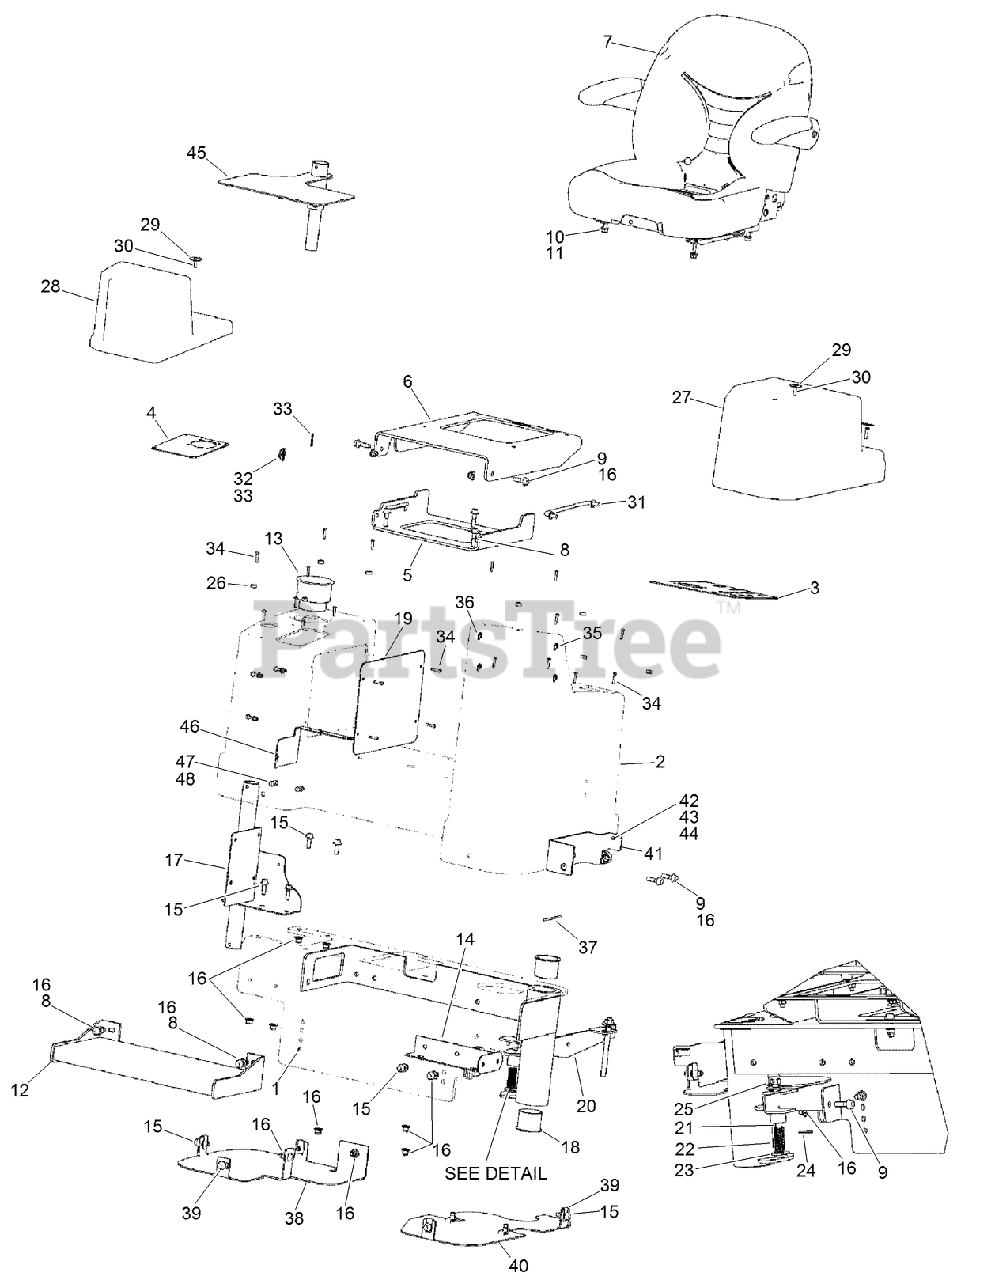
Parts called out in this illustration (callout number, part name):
1	WELDMENT - Operators Console
2	CONSOLE - Fiberglass
3	PLATE - Console/Switch
4	PLATE - Joystick Mount
5	PLATE - Seat Mount Bottom
6	PLATE - Seat Mount Top
7	OPERATOR SEAT ASM (STATIC)
8	SCREW-HHF
9	SCREW-HHF
10	WASHER - 0.406 x 0.750 x 0.119 in CST ZND
11	NUT - Hex .375 - 16 GR8 PHC
12	ASSEMBLY - Foot Rest
13	CUP-HOLDER
14	WELDMENT - Operators Console Support
15	SCREW-HH
16	NUT-FLANGE, NYLOCK
17	WELDMENT - Umbrella Mount
18	BEARING - Seat Pivot
19	PLATE - Seat Ins Panel
20	ARM - Seat Adjustment
21	ROD-SWING, SEAT
22	SPRING-PIVOT LOCK, SEAT
23	WASHER-FLAT
24	PIN-COTTER
25	NUT-Hex 0.500-13 GR5 ZND
26	GROMMET-RUBBER
27	COVER-PROTECTIVE, LEFT
28	COVER-PROTECTIVE, RIGHT
30	SCREW - Button Head (Allen)
31	ROD-PROP, SEAT
32	WASHER-FLAT
33	PIN - Cotter Hair Int 3/16 in ZND
34	SCREW - PHD Type 1, #10 - 24 x 1.00 CST ZND
35	SCREW - Hex Hd #10 - 24 x 0.875 CST PHC
36	NUT-#10-24 KEPS
37	PIN-COTTER
38	PLATE - Splash Guard
40	PLATE - Splash Guard
41	PLATE - Cord Retaining
42	CLIP - Tool
43	SCREW - PHd Type 1 #6 - 32 x 0.500 CST ZND
44	NUT - KEPS Ext T Wshr #6 - 32 UNC ZP
45	MOUNT - Locator
46	PLATE - Mount
47	SCREW, METRIC FLANGE w/BODY - M6 x 30
48	NUT, METRIC FLANGE PREVAILING - M6 Zinc
